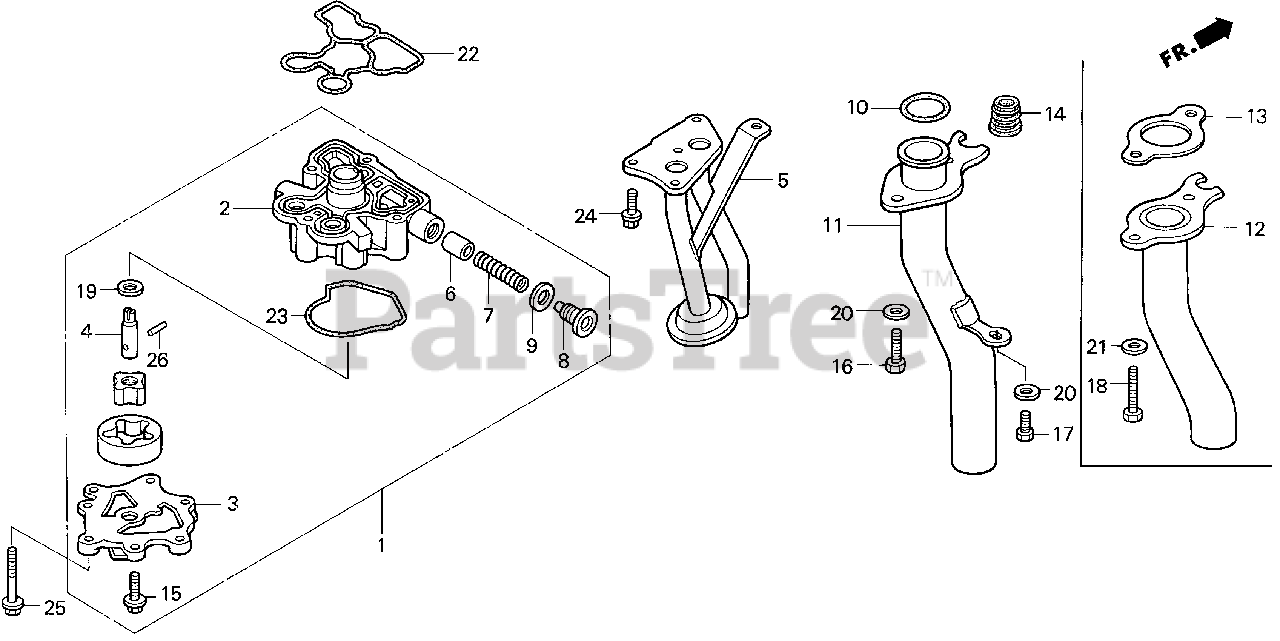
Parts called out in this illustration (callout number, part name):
1	PUMP ASSY., OIL
2	BODY, OIL PUMP
3	COVER, OIL PUMP
4	SHAFT, OIL PUMP
5	STRAINER, OIL
6	VALVE, RELIEF
7	SPRING, RELIEF VALVE
8	BOLT, SEALING (14MM)
9	WASHER, SEALING (14MM)
13	GASKET, EX. PIPE
14	GROMMET, WATER TUBE
15	BOLT, FLANGE (6X18)
18	BOLT, HEX. (8X25)
19	WASHER, THRUST (11MM)
21	WASHER, PLAIN (8MM)
22	O-RING, PUMP COVER
23	O-RING, PUMP COVER
24	BOLT, FLANGE (6X16)
25	BOLT, FLANGE (6X45)
26	ROLLER (4X15.8)
